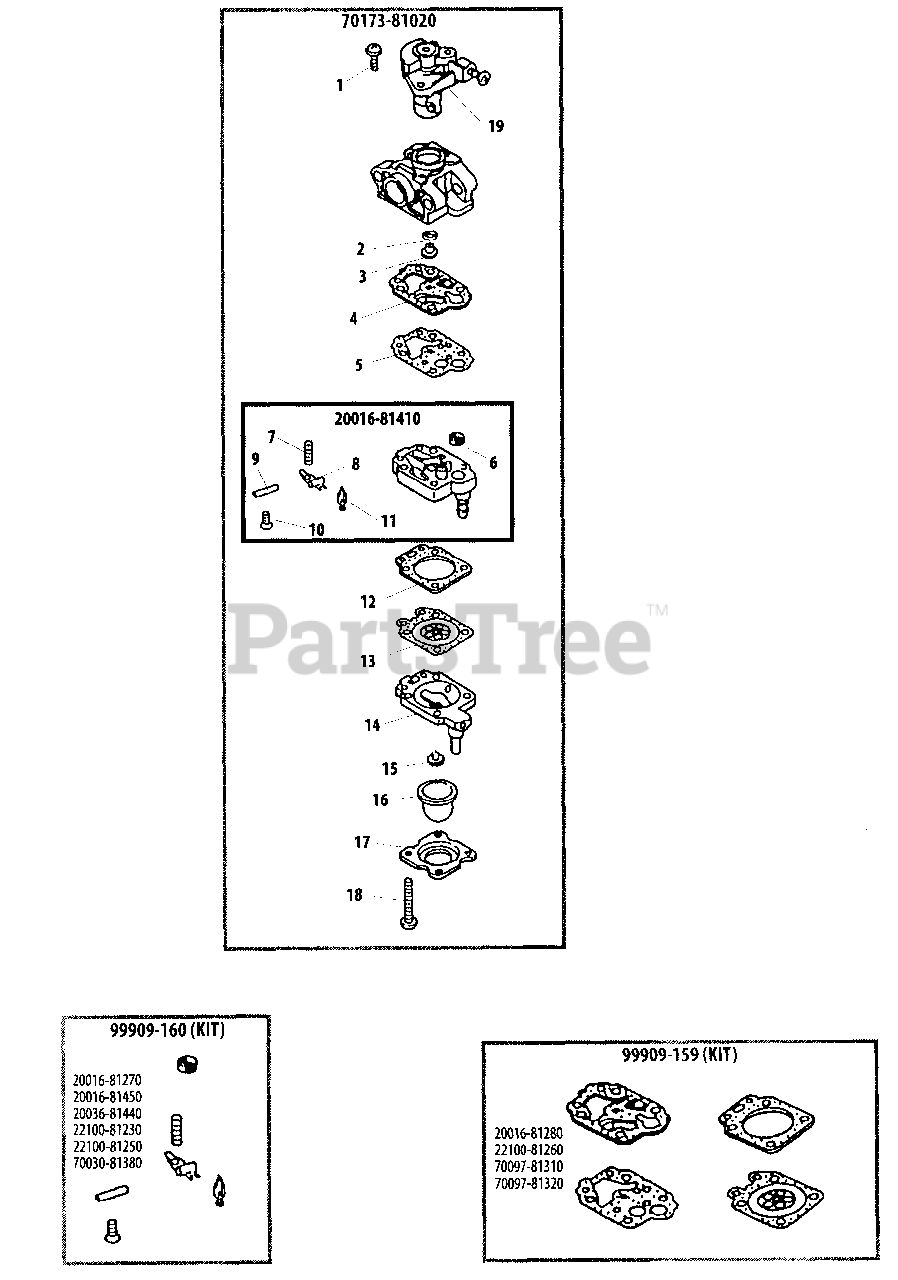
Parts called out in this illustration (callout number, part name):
1	SCREW, THROTTLE COLLAR
2	O-RING
3	MAIN JET - #38
4	GASKET, PUMP
5	DIAPHRAGM, PUMP
6	SCREEN, FUEL INLET
7	SPRING, METERING LEVER
8	LEVER, METERING
9	PIN, METERING LEVER
10	SCREW
11	VALVE, INLET NEEDLE
12	GASKET, METERING DIAPHRAGM
13	DIAPHRAGM, METERING
14	BODY ASSY, PURGE
15	VALVE, CHECK
16	BULB, PURGE
17	RETAINER, PURGE BULB
18	SCREW
19	THROTTLE VALVE ASSY
20016-81410	BODY ASSY, PUMP
70173-81020	CARBURETOR
99909-159	GASKET / DIAPHRAGM KIT
99909-160	VALVE KIT, INLET NEEDLE
